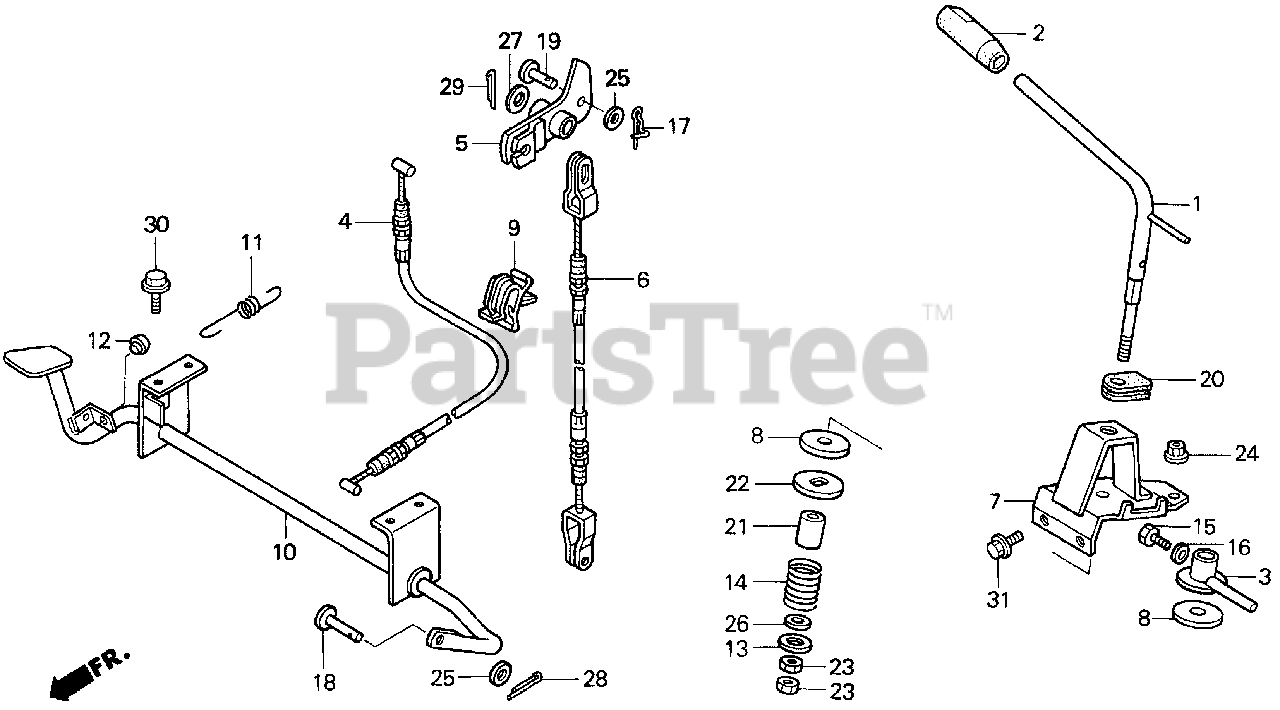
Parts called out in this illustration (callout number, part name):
1	LEVER, ACCELERATOR
2	GRIP, ACCELERATOR LEVER
3	ARM, ACCELERATOR LEVER
4	CABLE, ACCELERATOR
5	HOLDER, ACCELERATOR WIRE
6	CABLE, FOOT ACCELERATOR
7	BRACKET, ACCELERATOR
8	WASHER, LINING
9	CLIP, WIRE HARNESS
10	PEDAL, ACCELERATOR
11	SPRING, ACCELERATOR PEDAL
12	RUBBER B, STOPPER
13	PLATE, HANDLE SETTING
14	SPRING, SPLASH GUARD ADJUSTING (UPPER)
15	BOLT, SPECIAL (6X16)
16	WASHER, CONICAL SPRING (6MM)
17	PIN, SNAP (6MM)
18	PIN, P.T.O. CHANGE ROD
19	PIN, CLUTCH JOINT
20	GROMMET, THROTTLE LEVER
21	COLLAR, ACCELERATOR
22	WASHER, SPRING SETTING
23	NUT, HEX. (8MM)
24	NUT, FLANGE (6MM)
25	WASHER, PLAIN (6MM)
26	WASHER, PLAIN (8MM)
27	WASHER, PLAIN (10MM)
28	PIN, COTTER (1.6X25)
29	PIN, COTTER (2.5MM)
30	BOLT, FLANGE (6X12)
31	BOLT, FLANGE (6X14)
